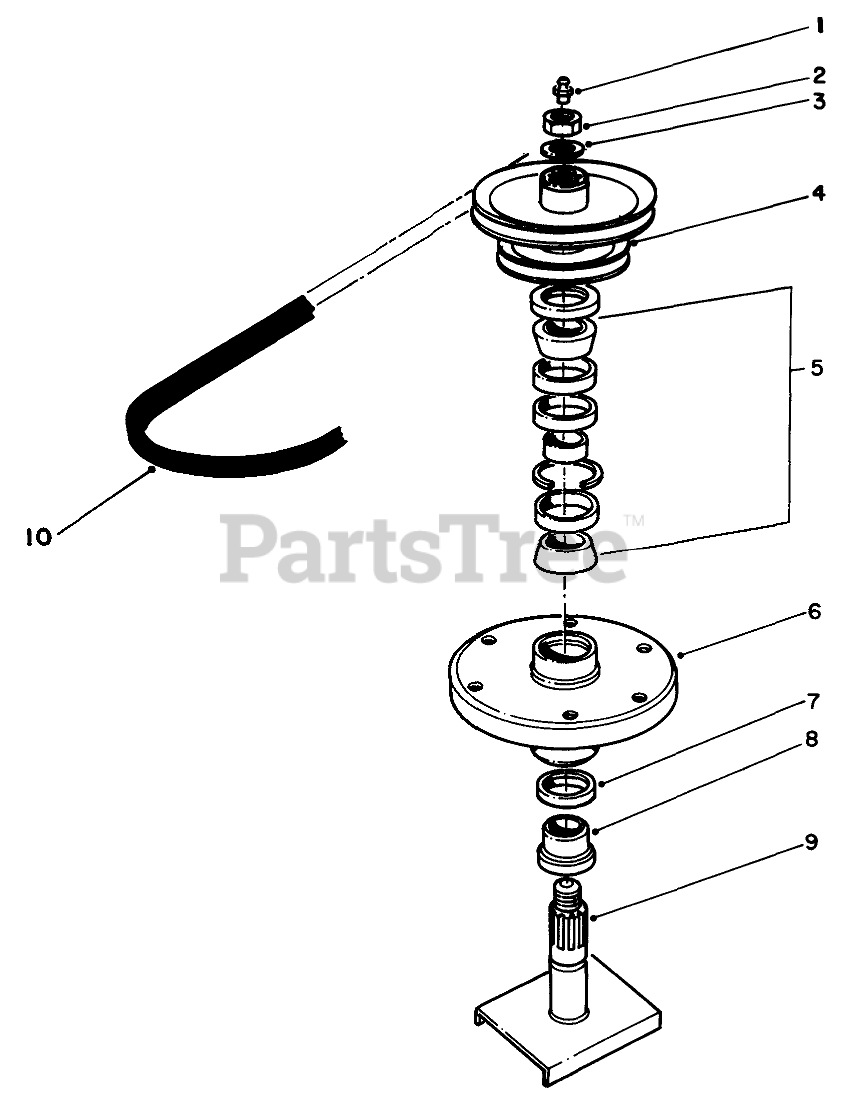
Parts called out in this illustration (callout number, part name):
1	FITTING-GREASE
2	NUT-HEX
3	WASHER
4	PULLEY AND HUB ASM
5	BEARING ASM
6	HOUSING-SPINDLE
7	SEAL-OIL
8	SPACER
9	Shaft-Spindle
10	V-BELT, DRIVE
